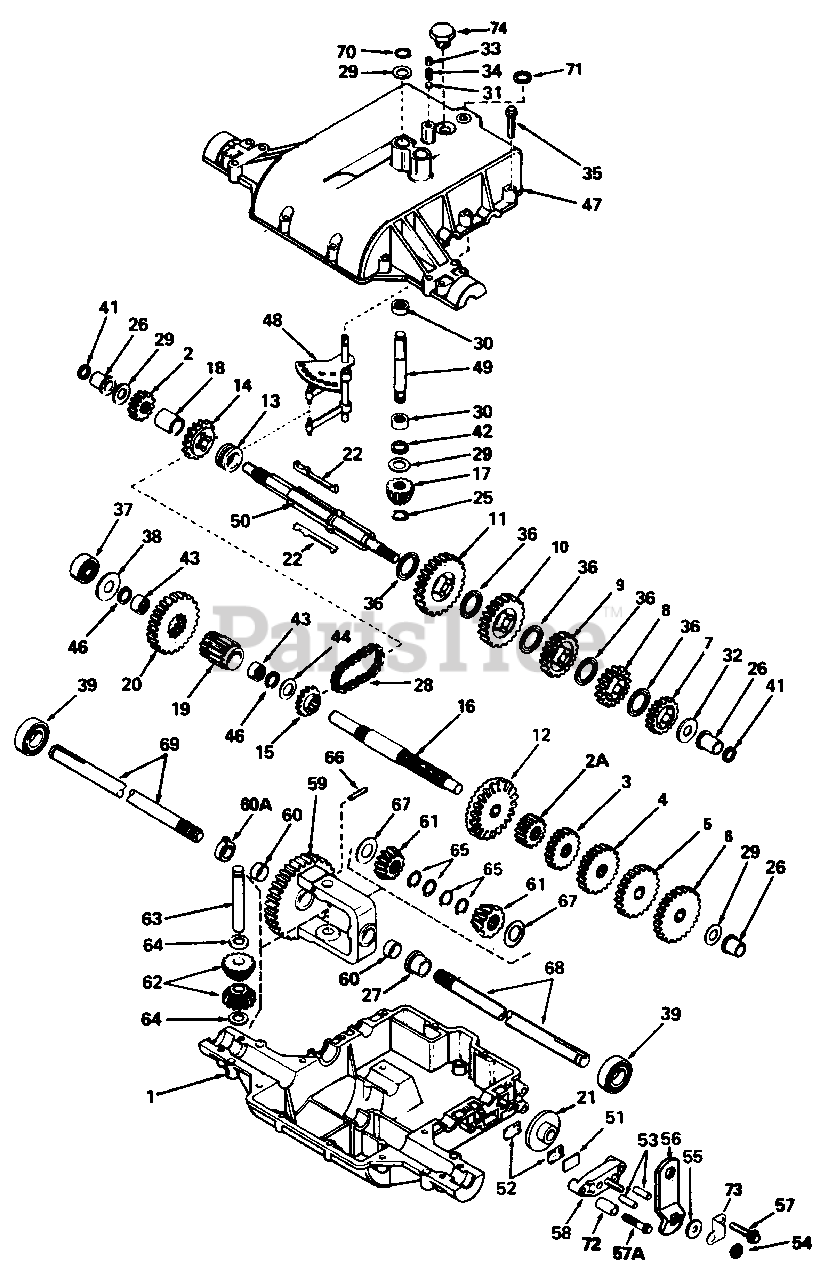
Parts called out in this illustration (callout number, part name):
1	CASE, Transaxle
2	GEAR, Spur (15 Teeth)
2A	GEAR, Spur (12 Teeth)
3	GEAR, Spur (20 Teeth)
4	GEAR, Spur (25 Teeth)
5	GEAR, Spur (28 Teeth)
6	GEAR, Spur (30 Teeth)
7	GEAR, Spur (20 Teeth)
8	GEAR, Spur (22 Teeth)
9	GEAR, Spur (25 Teeth)
10	GEAR, Spur (30 Teeth)
11	GEAR, Spur (37 Teeth)
12	GEAR, Bevel (42 Teeth)
13	COLLAR, Shift
14	SPROCKET (14 Teeth)
15	SPROCKET (10 Teeth)
16	SHAFT, Counter
17	BEVEL PINION, Input
19	PINION, Output
20	GEAR, Output
21	DISK, Brake
25	RING, Retaining
26	BUSHING, Flanged
27	BUSHING, Flanged
28	CHAIN, Roller (No. 41 Chain, 22 Links)
29	WASHER, Thrust
30	BEARING, Needle
31	BALL, Steel
32	WASHER, Thrust
33	SCREW, Set, 3/8-16 x 3/8
35	SCREW, Hex Hd., Thread Forming, 1/4-20 x 1-1/4
36	WASHER, Thrust
37	BEARING, Ball
38	WASHER, Flat
39	BEARING, Ball
41	SEAL, Square Cut
42	SEAL, Square Cut
43	BEARING, Needle
44	WASHER, Flat
46	SEAL, Square Cut
47	COVER, Transaxle
48	ROD & FORK ASSY., Shift
49	SHAFT, Input
50	SHAFT, Brake
51	PLATE, Brake Pad
52	PAD, Brake
53	PIN, Dowel
54	LOCKNUT, 5/16-24
55	WASHER, Flat
56	LEVER, Brake
57	SCREW, Hex Hd., Thread Forming, 1/4-20 x 1-1/4
57A	SCREW, Hex Hd., Thread Forming, 1/4-20 x 2-1/4
58	HOLDER, BrakePad
59	GEAR ASSY., Differential (Incl. 2 of Ref. No. 60)
61	GEAR, Bevel
62	PINION, Bevel
63	PIN, Drive
64	WASHER, Thrust
65	RING, Retaining (Pkg. of 2)
66	PIN, Roll
67	WASHER, Thrust
68	AXLE (14-3/8" Long)
69	AXLE (12-1/2" Long)
70	RING, Retaining
71	SEAL, Square Cut
73	BRACKET, Brake Lever
74	PLUG, Threaded
